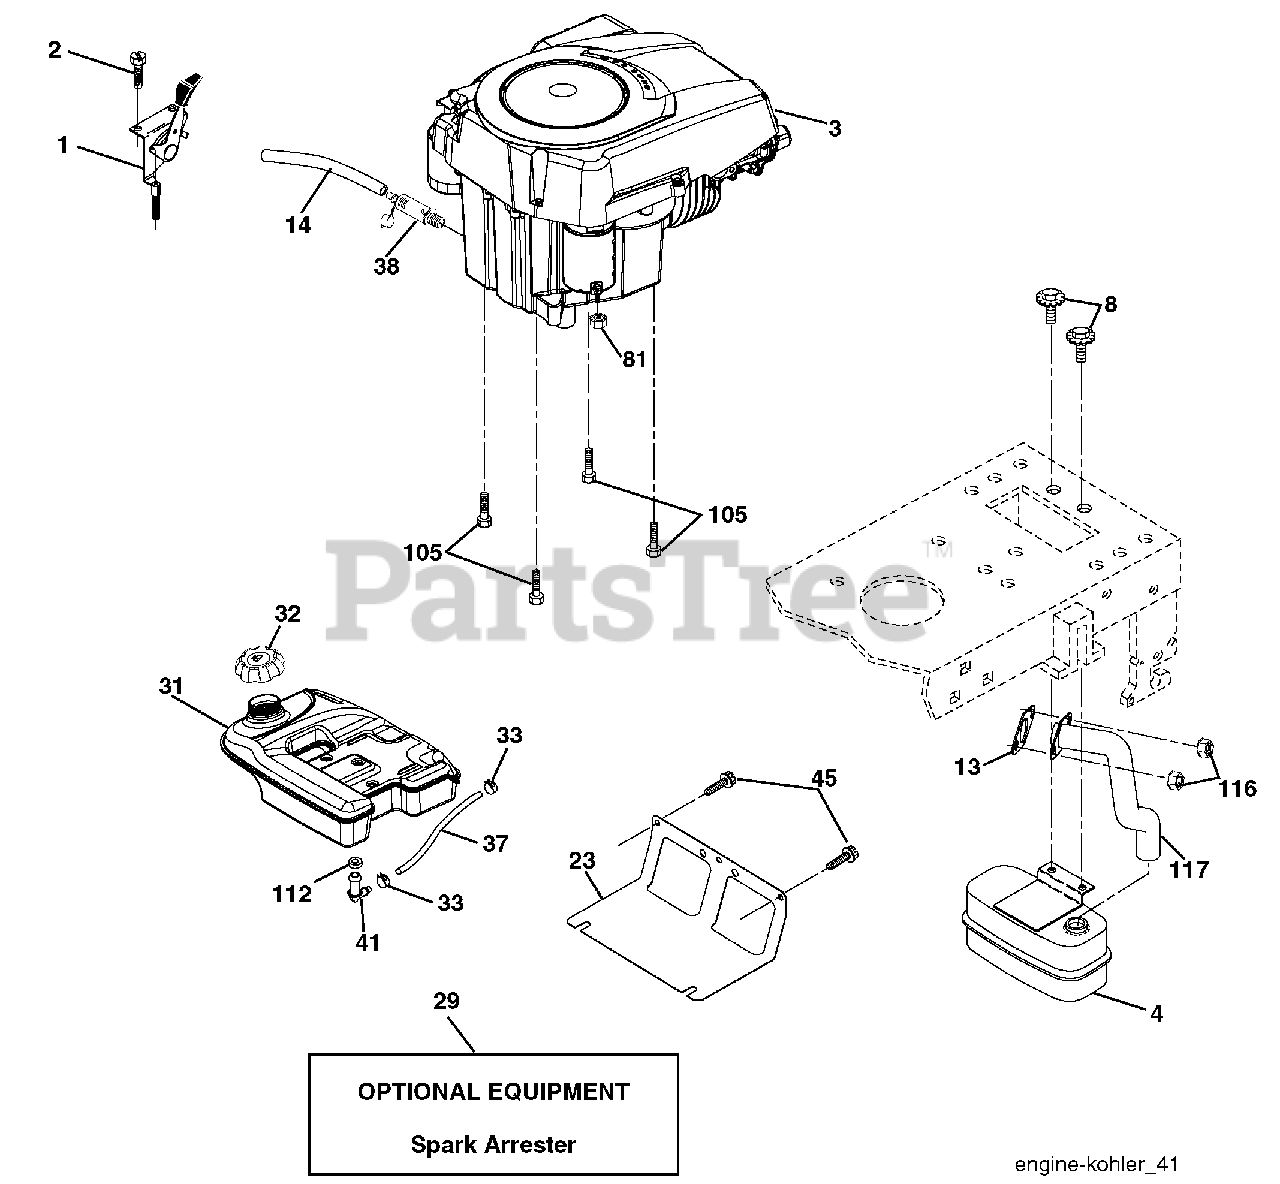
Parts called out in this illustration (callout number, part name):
1	Control, Throttle/Choke
2	Screw Hex Thd Cut 1/4-20 x 1/2
4	Muffler
8	Bolt 5/16-18 unc x 3/4 w/Sems
13	Muffler Gasket
14	Tube Oil Drain
23	Shield, Browning/Debris Guard
29	Arrester, Spark
31	Tank, Fuel
32	Cap Gauge, Fuel
33	Clamp, Hose Blk
37	Line, Fuel
38	Plug Drain Oil Easy
41	Stem Tank Fuel
45	Screw Hex Wsh Thdrol 3/8-16 x 3/4
81	Nut Keps Hex 1/4-20 UNC
105	Screw 3/8-16 x 1
112	Bushing
116	Nut Hex Flange Toplock M8-1.25
117	Tube Exhaust
